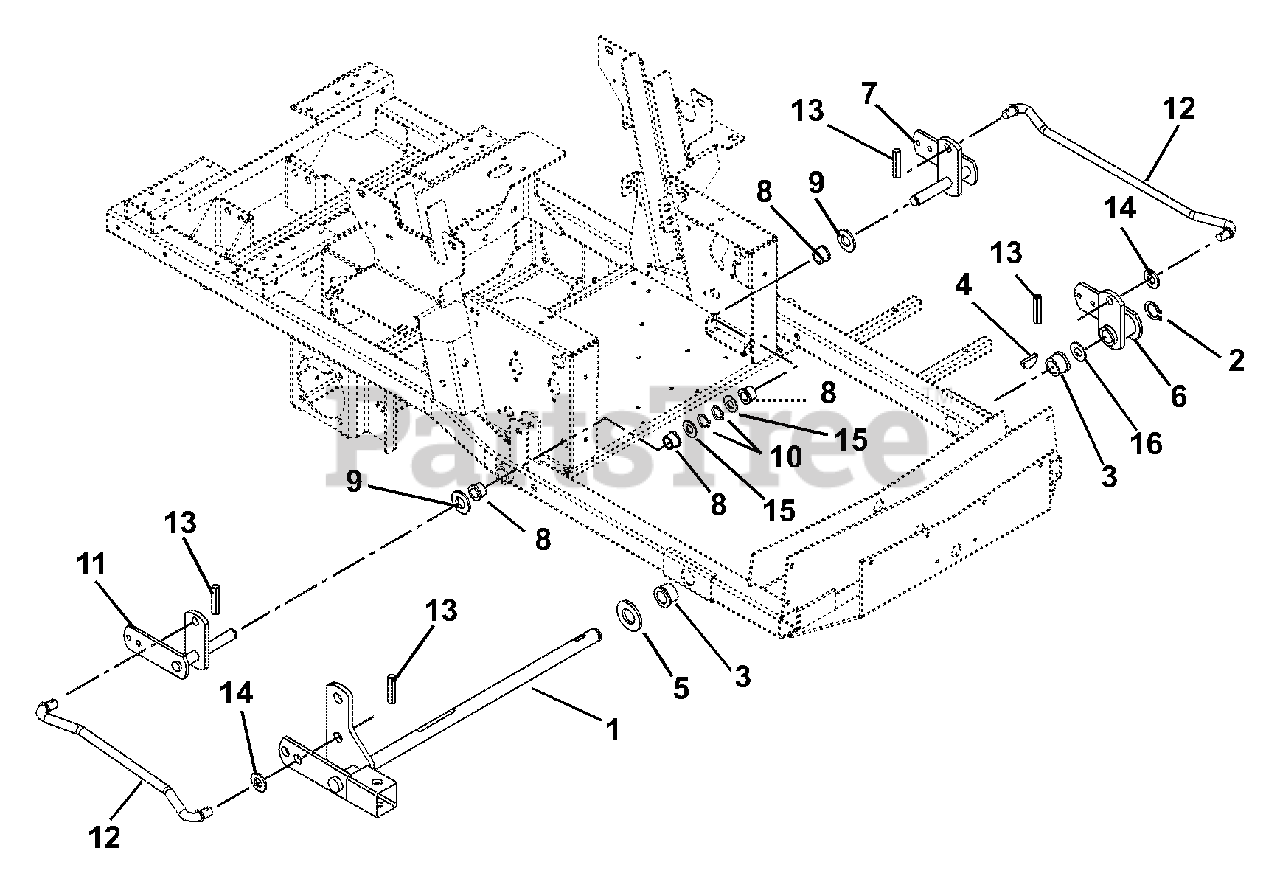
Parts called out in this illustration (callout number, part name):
1	Lift, Mower
2	Ring, Retaining External 1.00 x .078
3	Bushing, Flange Nylon 1.02 x 1.385 x .75 x 1.75
4	Key, Woodruff .25 x 1.00
5	Washer, Flat Steel 1.063 x 2.00 x .134
6	Weldment, Lift Arm-Front
7	Weldment, Rear Lift Arm-Left Hand
8	Bushing, Flange Nylon .762 x 1.0 x .58 x 1.48
9	Washer, Hardened Steel .758 x 1.23 x .031
10	Ring-Retaining-External .689 x .077
11	Weldment, Rear Lift Arm- Right Hand
12	Rod, Lift Assist 19.35"
13	Pin, Roll .25 x 1.25 Stainless Steel
14	Washer, Flat Steel .630 x 1.25 x .062
15	Washer, Flat Steel .755 x 1.25 x .125
16	Washer, Hardened Thrust 1.00 x 1.55 x .03
